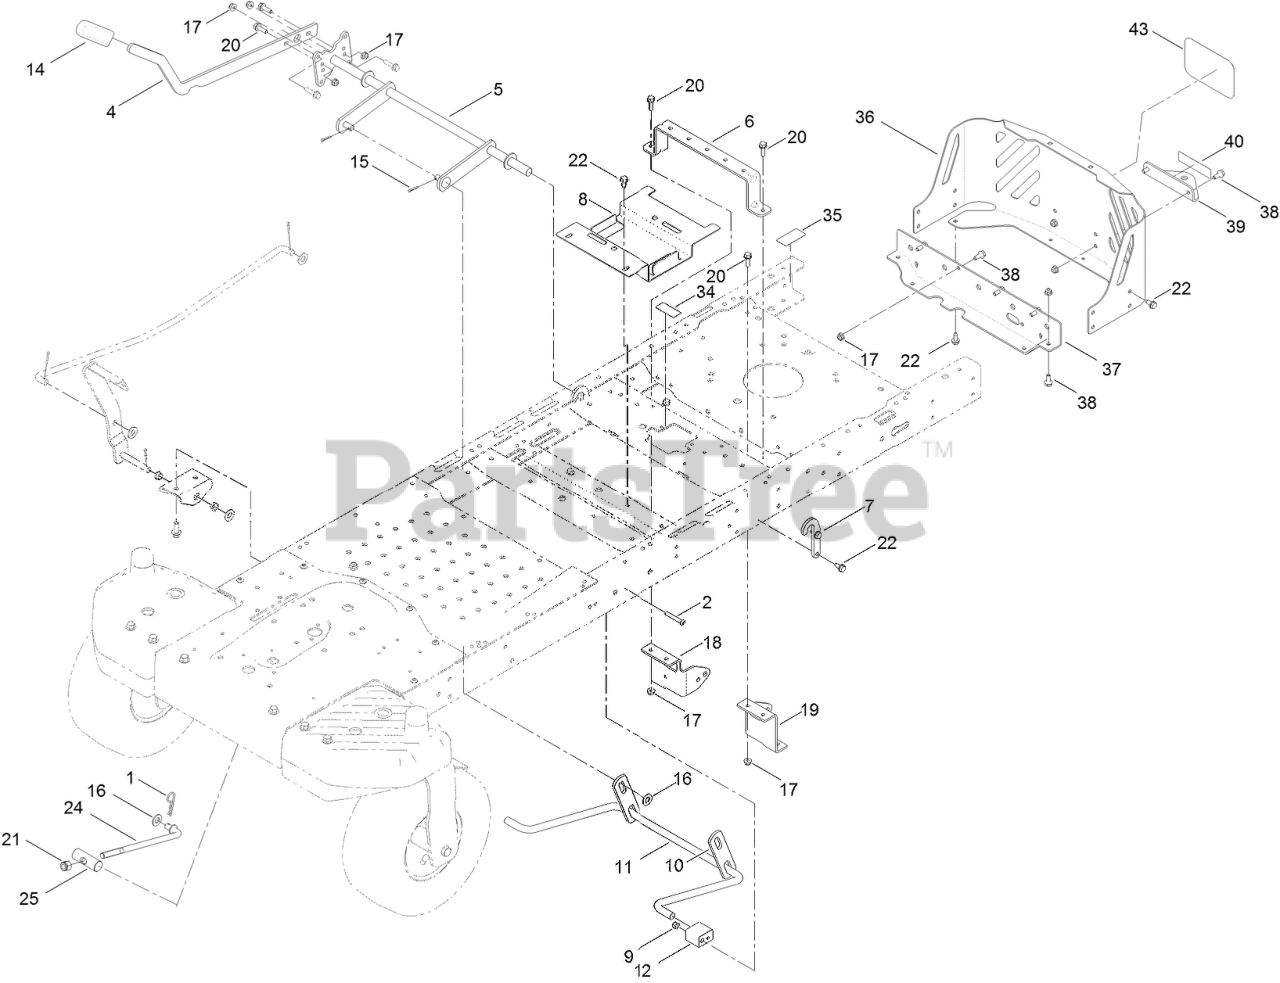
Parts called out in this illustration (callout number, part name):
1	PIN-COTTER
2	SCREW-HSBH
4	LEVER-LIFT
5	LIFT-DECK, NARROW
6	BRACE-SEAT, REAR (NARROW)
7	BRACKET-LIFT
8	BRACKET-BATTERY
9	NUT-LOCK, NI
10	LINK-LIFT
11	ARM-LIFT, REAR
12	BLOCK-PIVOT
14	GRIP-LEVER
15	PIN-COTTER
16	WASHER-FLAT
17	NUT-HF, NI
18	MOUNT-HYDRO, FRONT (RH)
19	MOUNT-HYDRO, FRONT (LH)
20	SCREW-HHF
21	NUT-HEX
22	SCREW-HWHTF
24	ROD-MOUNT, DECK
25	PIN-PIVOT
34	DECAL-LOCATION, SERVICE DEALER
35	DECAL-BYPASS
36	GUARD-ENGINE, NARROW
37	CROSSMEMBER-REAR, NARROW
38	SCREW-HHF
39	BRACKET-HITCH
43	DECAL
